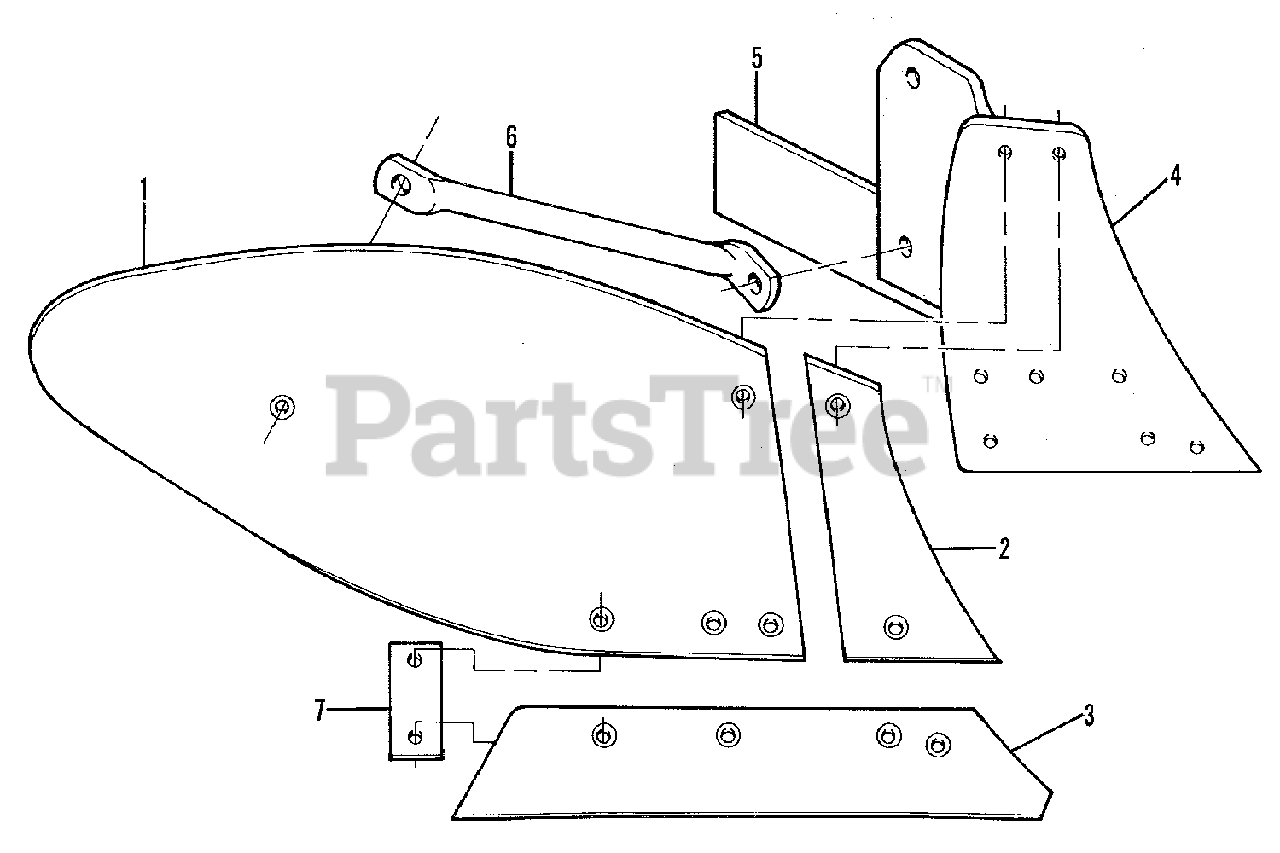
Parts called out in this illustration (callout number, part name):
1	MOLDBOARD (14")
1	BOLT, Plow, No. 3 Head, 7/16NC x 1-1/2
1	WASHER, Plain, 11/16 x 1-3/4 x 10 Ga.
1	NUT, 7/16NC
2	BOLT, Plow, No. 3 Head, 7/16NC x 1-1/2
2	NUT, 7/16NC
3	BLADE (14")
3	BOLT, Plow, No. 3 Head, 7/16NC x 1-1/2
3	NUT, 7/16NC
4	FROG ASSEMBLY (14")
5	LANDSIDE (14")
5	BOLT, Plow, No. 3 Head, 7/16NC x 1-1/2
5	NUT, 7/16NC
6	BRACE (14")
7	BLOCK, Attaching
